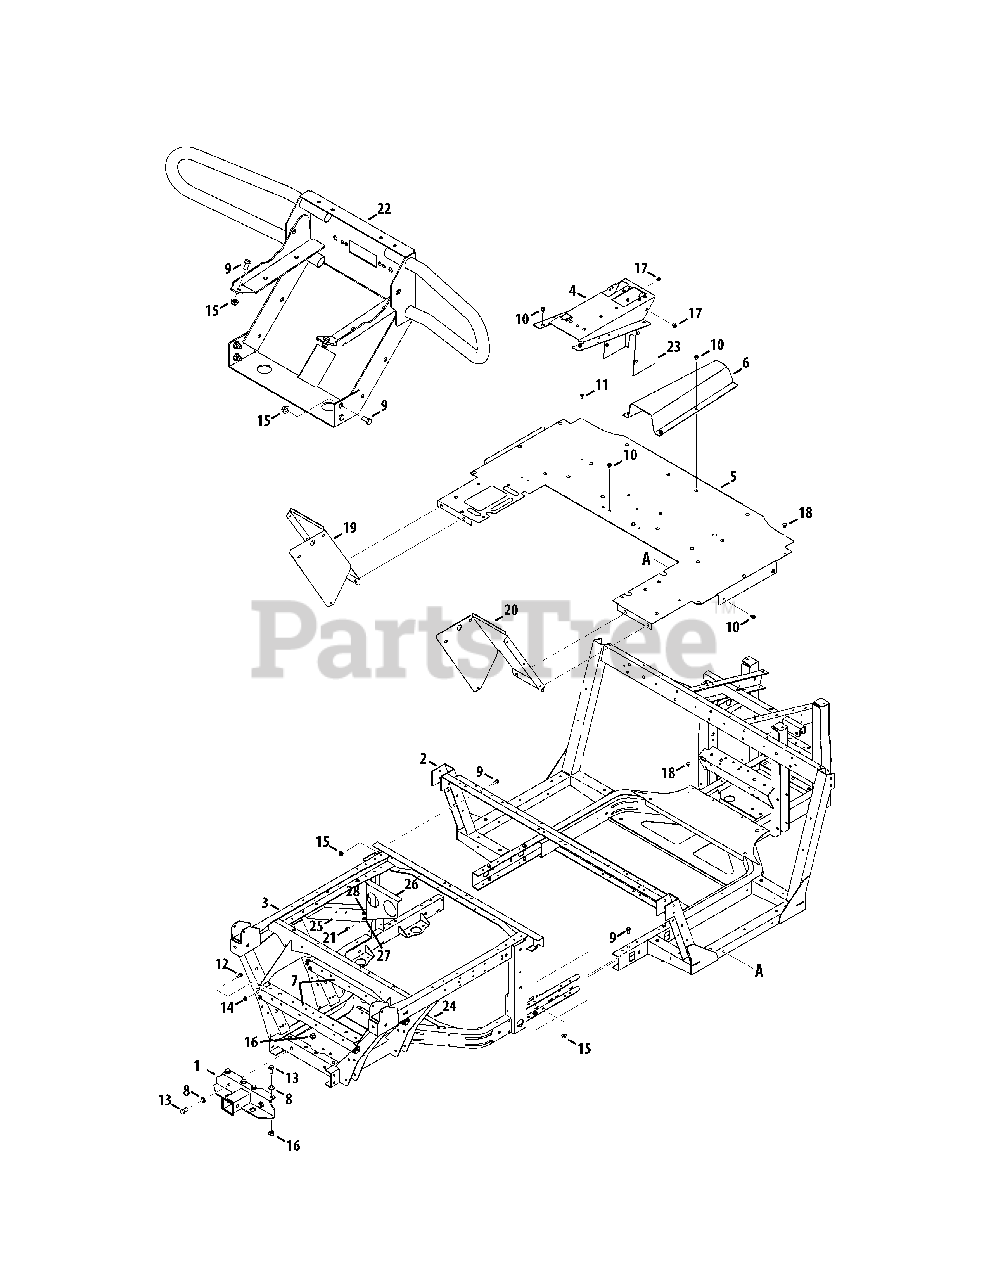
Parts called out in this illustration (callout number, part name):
1	Hitch Assembly, receiver Rr
2	Frame Assembly, front, uv
3	Frame Assembly, rear, uv
4	Plate, console, 4x4, top
6	Cover, front, 4x4
8	Washer, Flat, .510 x 1.00 x .060
9	Screw, 3/8-16 x .75, gr5, std
10	Screw, tt, 5/16-18 x 0.750
11	Screw, ab, 1/4-14, 0.625
12	Hex Head Screw, 5/16-18 (4x2)
12	Screw, Hxflg, 5/16-18 (4x4)
13	Screw, 1/2-13, 1.00, gr5, std
14	Nut, Flange Lock, 5/16-18, Nylon
15	Nut, Flange Lock, 3/8-16, Nylon
16	Nut, Hex Lock, 1/2-13, Nylon
17	Screw, tt, 5/16-18 x 0.500
18	Clip, Panel, ret,
19	Bracket, Lh, Shield
20	Bracket, Rh, Shield
21	Screw, tt, 1/4-20 x .500
23	Plate, console, 4x4, front
24	Bracket Assembly, ISO, Trans/ Eng
25	Bracket Assembly, Air Filter Mnt
26	Bracket Assembly, Supt, Hose
27	Hex Head Screw, 1/4-20 x .620
28	Nut, Flange Lock, 1/4-20
